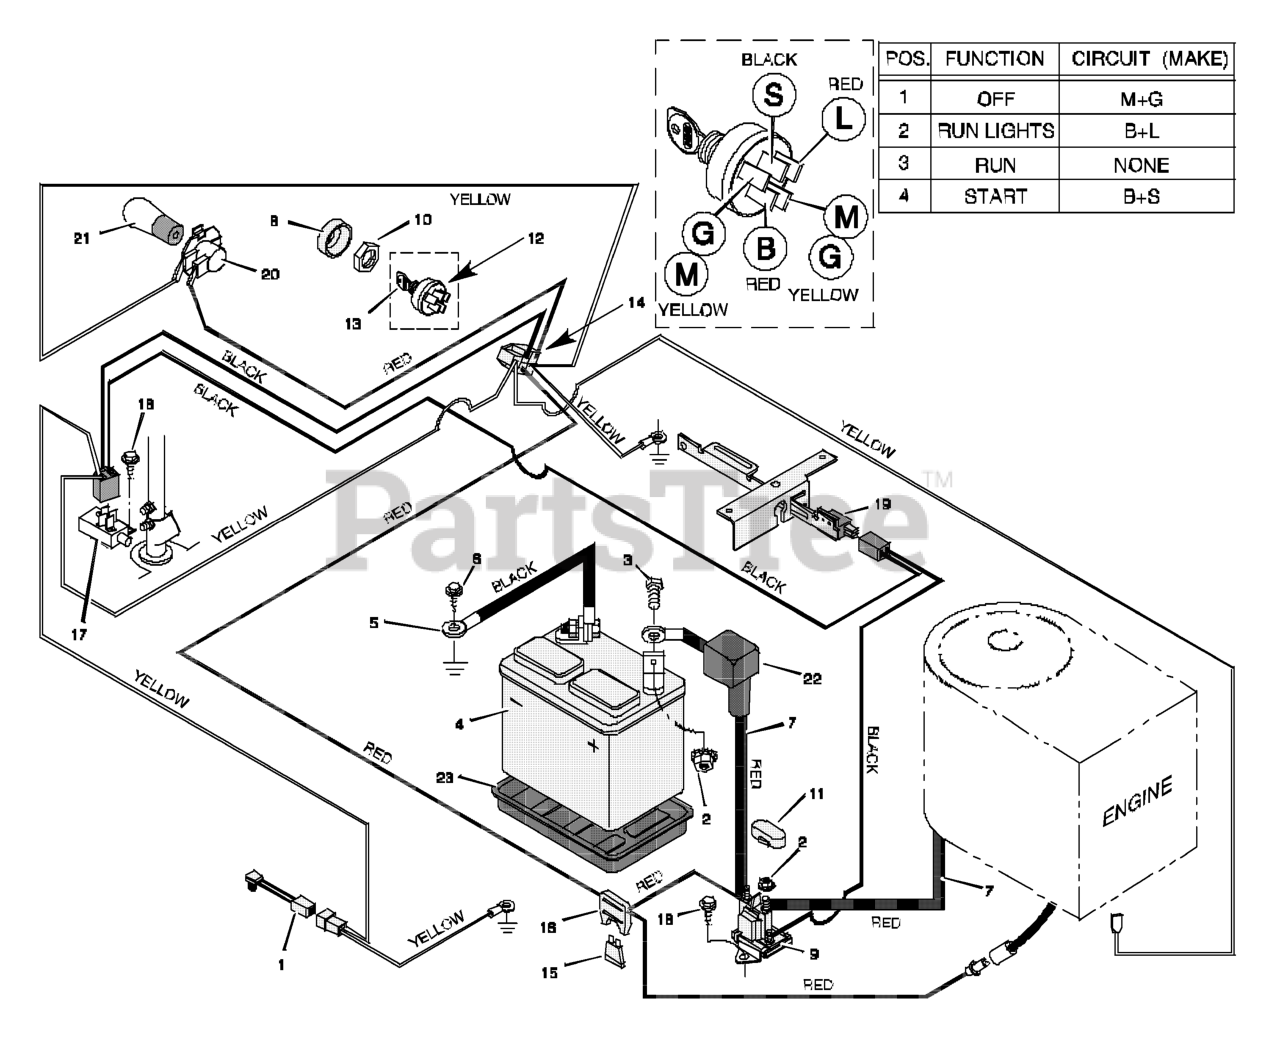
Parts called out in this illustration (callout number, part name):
1	Switch, Seat Sensor
2	Locknut
4	Battery
5	Cable, Battery Ground
7	Cable, Red Battery
8	Cap, Ignition
9	Solenoid
10	Nut, Hex
11	Cover, Solenoid
12	Switch, Ignition
13	Key, Ignition
14	Harness, Chassis, Wire
16	Holder, Fuse
17	Switch, Limit
19	Switch, Limit
20	Socket, Light
21	Bulb, Light
22	Cover, Terminal
23	Tray, Battery
